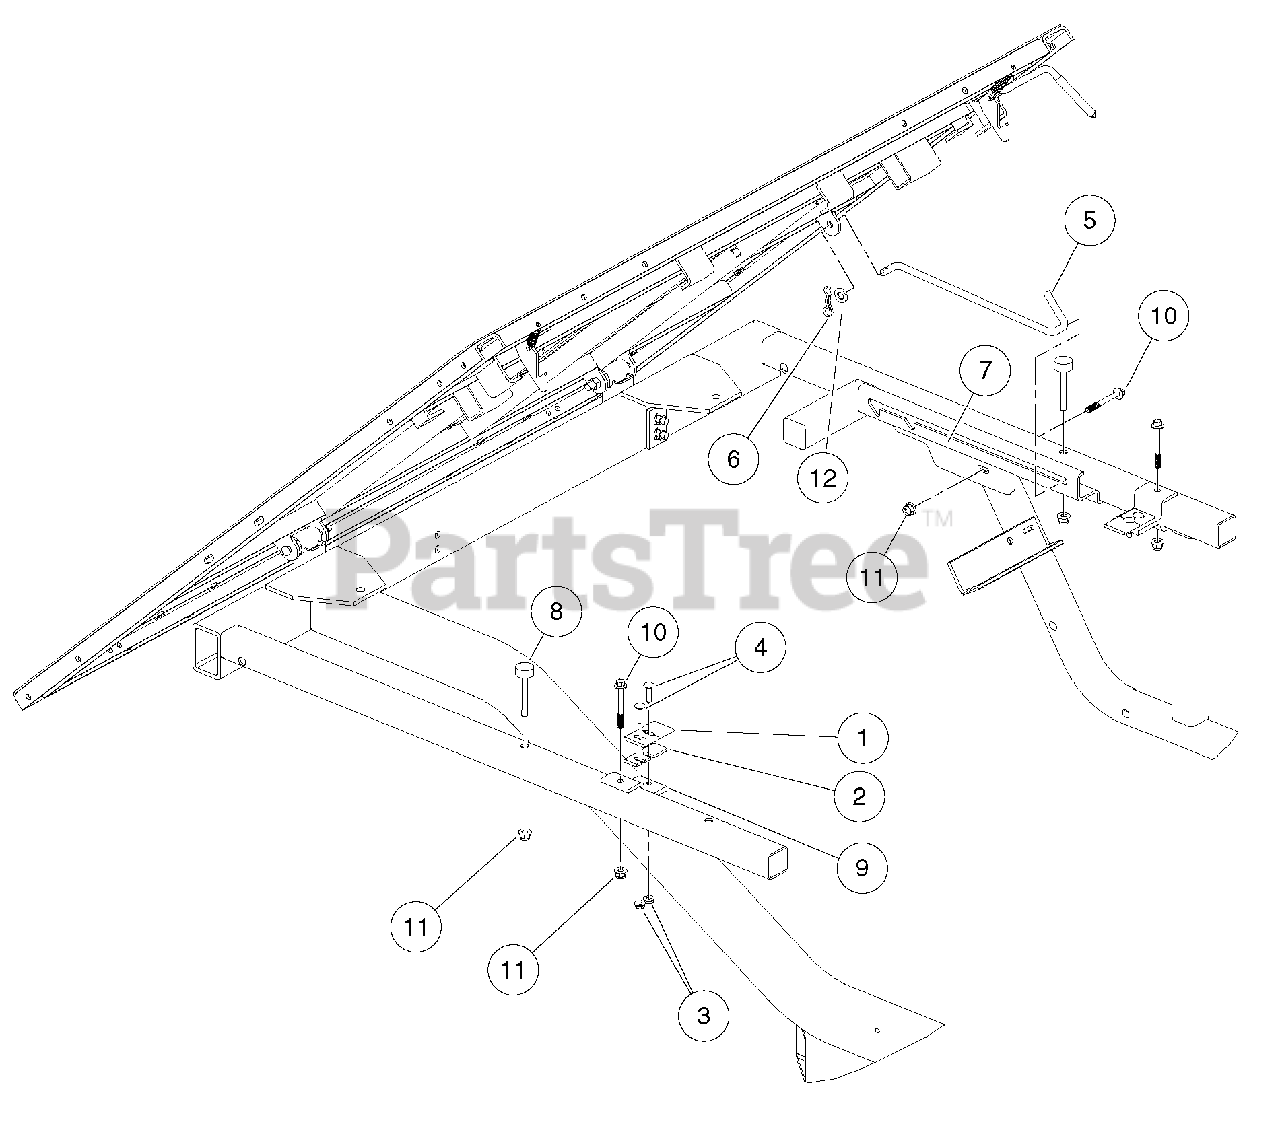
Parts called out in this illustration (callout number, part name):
1	Latch Plate, Tilt Bed
2	Latch Plate Shim
3	Locknut, 1/4-20 Hex Whiz
4	Bolt, Carriage, 1/4-20 X 1.0
6	Pin, Bow Tie Locking
7	Track, Prop Rod
8	Bumper, Bed, Mtg, Front
9	Bracket, Latch, Bed
10	Bolt Flanged Head, M8 X 1.25 X 65
11	Lock Nut, Flg M8 X 1.25 Nylon
12	Washer, 3/8 Type A Flat
